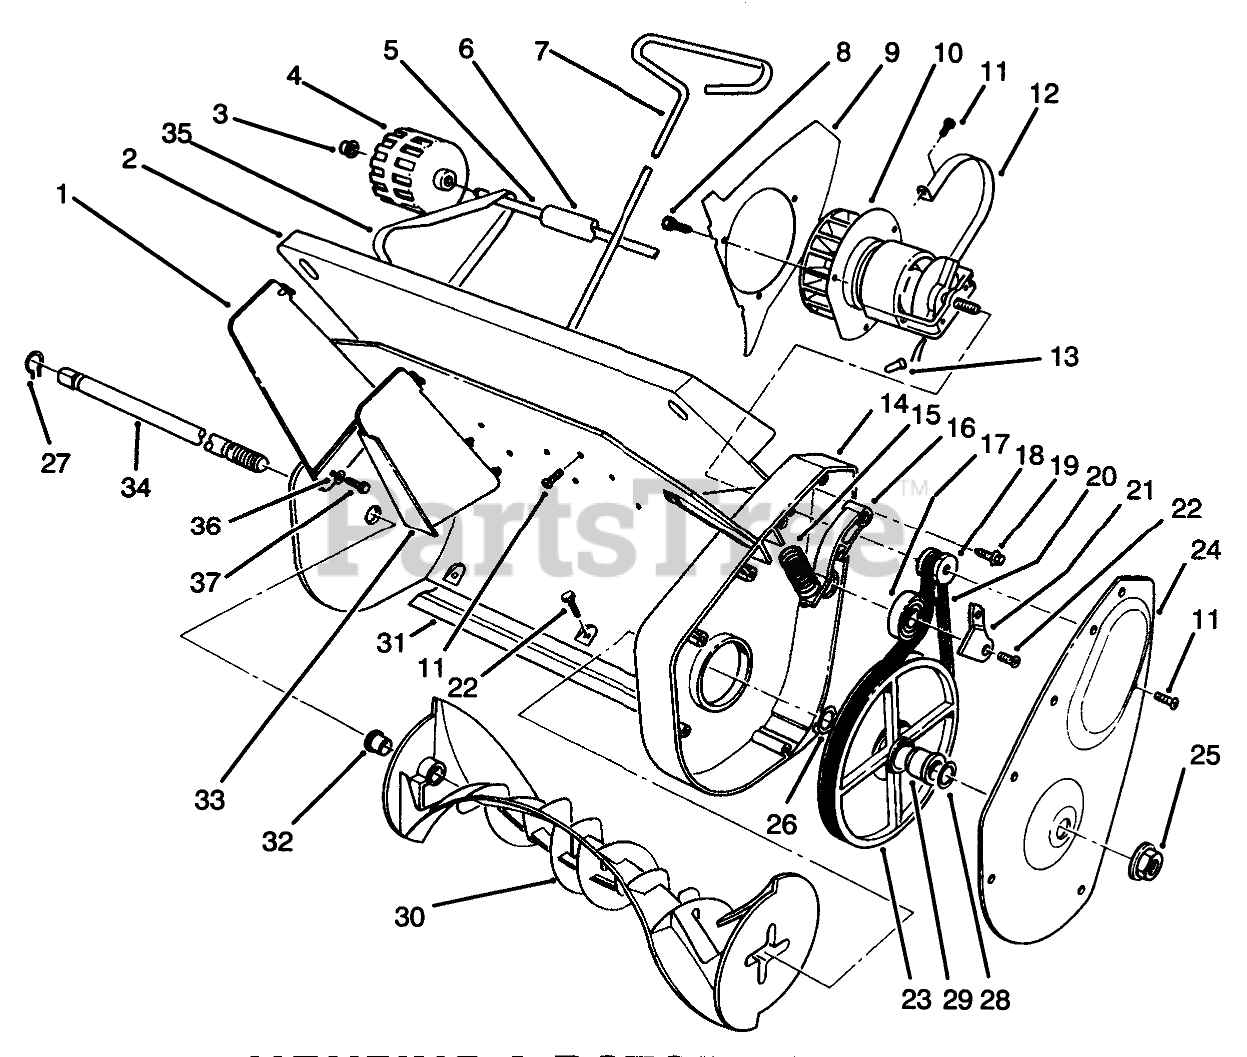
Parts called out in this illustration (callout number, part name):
1	VANE - OUTER
2	MOUNT - VANE
3	PUSHNUT-CAP, WASHER
4	Wheel
5	AXLE SHAFT
6	SLEEVE, AXLE
7	VANE ADJUSTING ROD
8	10-16 X .31 SCREW
9	AIR BAFFLE
10	MOTOR, 1200 PWR CURVE
11	Screw
12	MOTOR STRAP
13	Connector
14	HOUSING - 1200
15	SPRING
16	1200 PC - IDLER ARM
17	Bearing-Ball
18	DRIVE PULLEY
19	SCREW-HWHTF
20	BELT - DRIVE
21	1200 PC-IDLER PULL. RET
22	SCREW-PPH
23	PULLEY - DRIVEN
24	Belt Case Cover
25	NUT-HF
26	WASHER-THRUST
27	RING-RETAINING
28	THRUST WASHER (THICK)
29	DRIVEN PULLEY BUSHING
30	ROTOR, 1200
31	1200 SCRAPER, 12"
32	BUSHING-ROTOR
33	VANE - CENTER
34	ROTOR SHAFT, 1200
35	BRACKET-WHEEL,RH
36	WASHER-FLAT
37	SCREW-PPH
